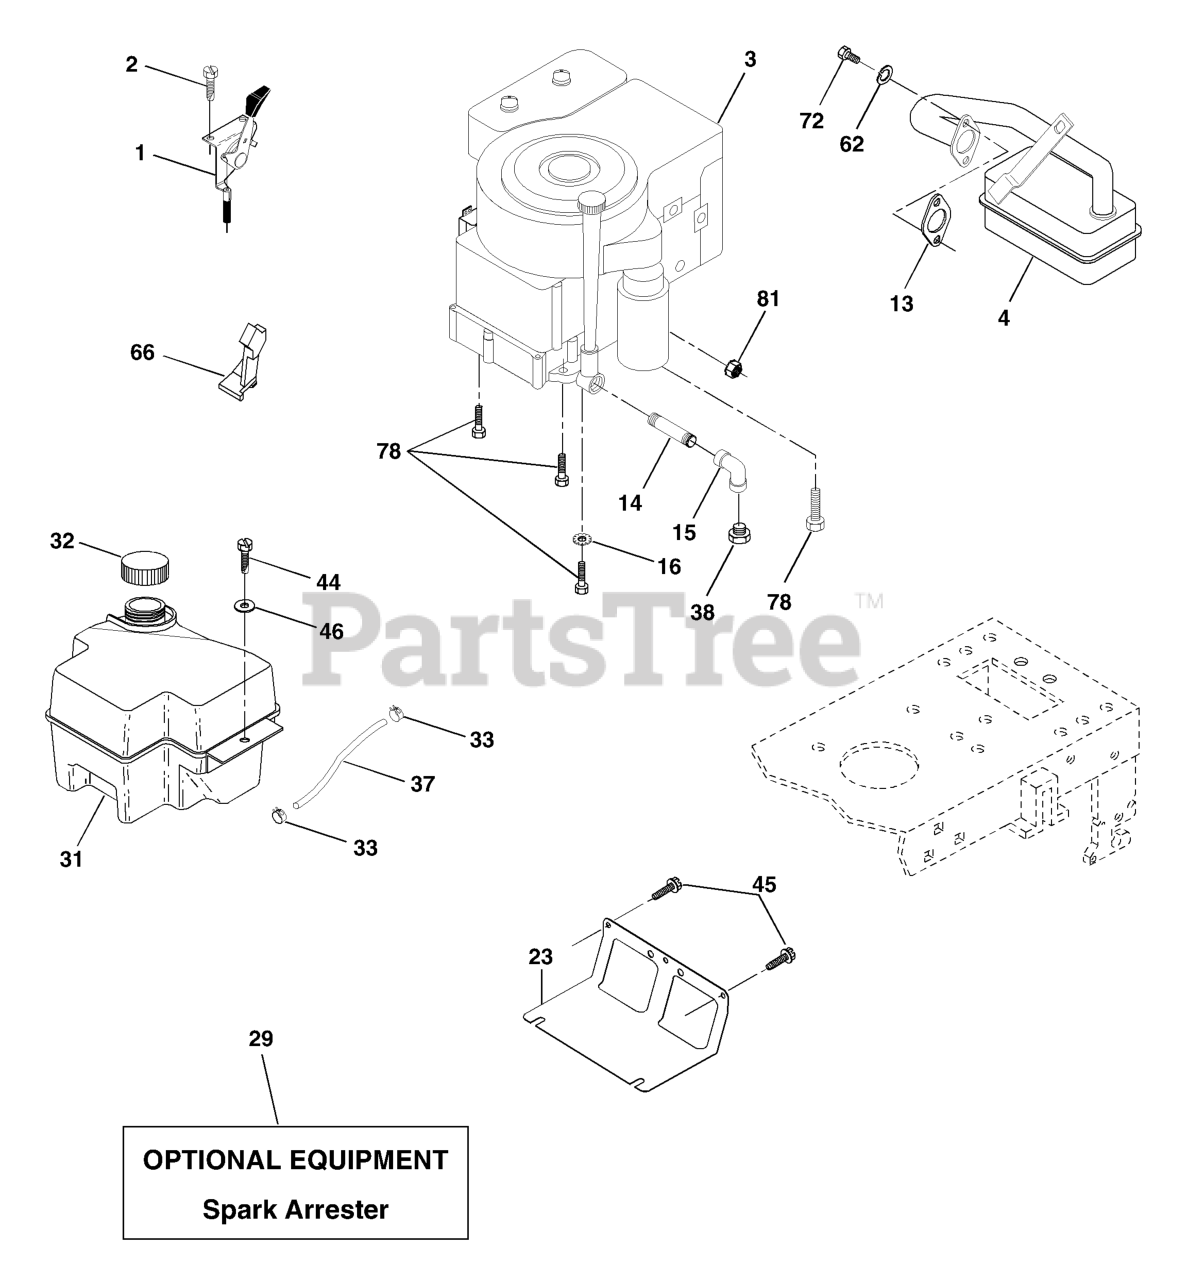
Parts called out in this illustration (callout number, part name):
1	CONTROL
2	SCREW LT
4	MUFFLER.SINGLE.B&S.10-12HP
13	REPL BY 532 27 22-93
14	Nipple Pipe 3/8 Npt X 3"
15	ELBOW
16	LOCKWASHER
23	SHIELD.BROWNING.DBR.GUARD
29	KIT.SPARK ARRESTOR 794945 B&S
31	FUEL TANK
32	FUEL CAP
33	HOSE CLAMP
37	LINE.FUEL.20
38	Plug Oil Drain
44	SCREW HEX CRT
45	SCREW 3/8-16X3/4
46	WASHER
62	WASHER.LOCK.HVY.HLCL.SPR.5/16
66	STOP THROTTLE
72	Screw Hexhd Cap 5/16-18 x 5/8
78	SCREW.3/8-16
81	NUT FLANGE 1/4-20 STARTER NUT
